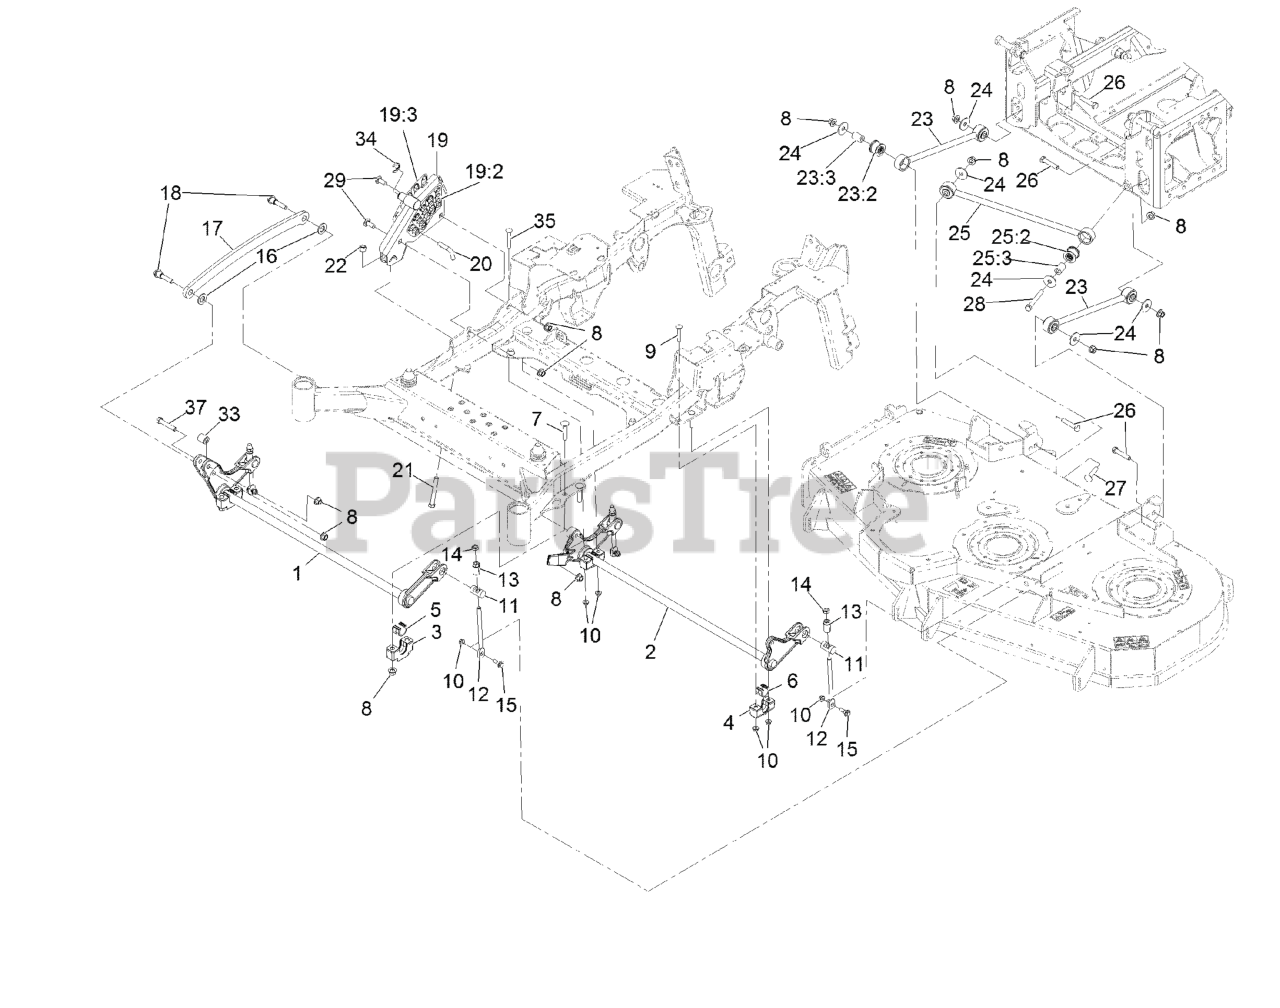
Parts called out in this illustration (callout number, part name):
1	DECKLIFT-FRONT
2	LIFT-DECK, REAR
3	SUPPORT-CROSS SHAFT, BEARING
4	SUPPORT-CROSS SHAFT, BEARING REAR
5	BEARING-CROSS SHAFT, FRON
6	BEARING-CROSS SHAFT, REAR
7	Bolt-Carriage 1/2-13 X 2 1/2 Spl Neck
8	Nut-Lock 1/2-13
9	Bolt-Carriage 3/8-16 X 2 1/4
10	NUT-HF, NI
11	TRUNNION
12	LINK-ADJUSTER, DECK LIFT
13	ADJUSTER-LIFT, DECK
14	NUT-JAM
15	SCREW-SHOULDER, HHF
16	WASHER-FLAT
17	LINK-LIFT, DECK
18	SCREW-HHF, SHOULDER
19	HOC ASM
19:2	DECAL-HEIGHT OF CUT
19:3	DECAL-HEIGHT OF CUT, OUTER
20	PIN-HOC
21	BOLT-TAP
22	NUT-LOCK, NI
23	DECK STRUT ASM
23:2	BUSHING-SUSPENSION, RUBBER
24	WASHER-THRUST
25	PANHARD ROD ASM
25:2	BUSHING-SUSPENSION, RUBBER
26	SCREW-HH
27	SCREW-CARR
28	SCREW-HH
29	SCREW-CARR, SHORT NECK
33	SPACER-PIVOT
34	RING-RETAINING
35	SCREW-CARR
37	SCREW-HH
